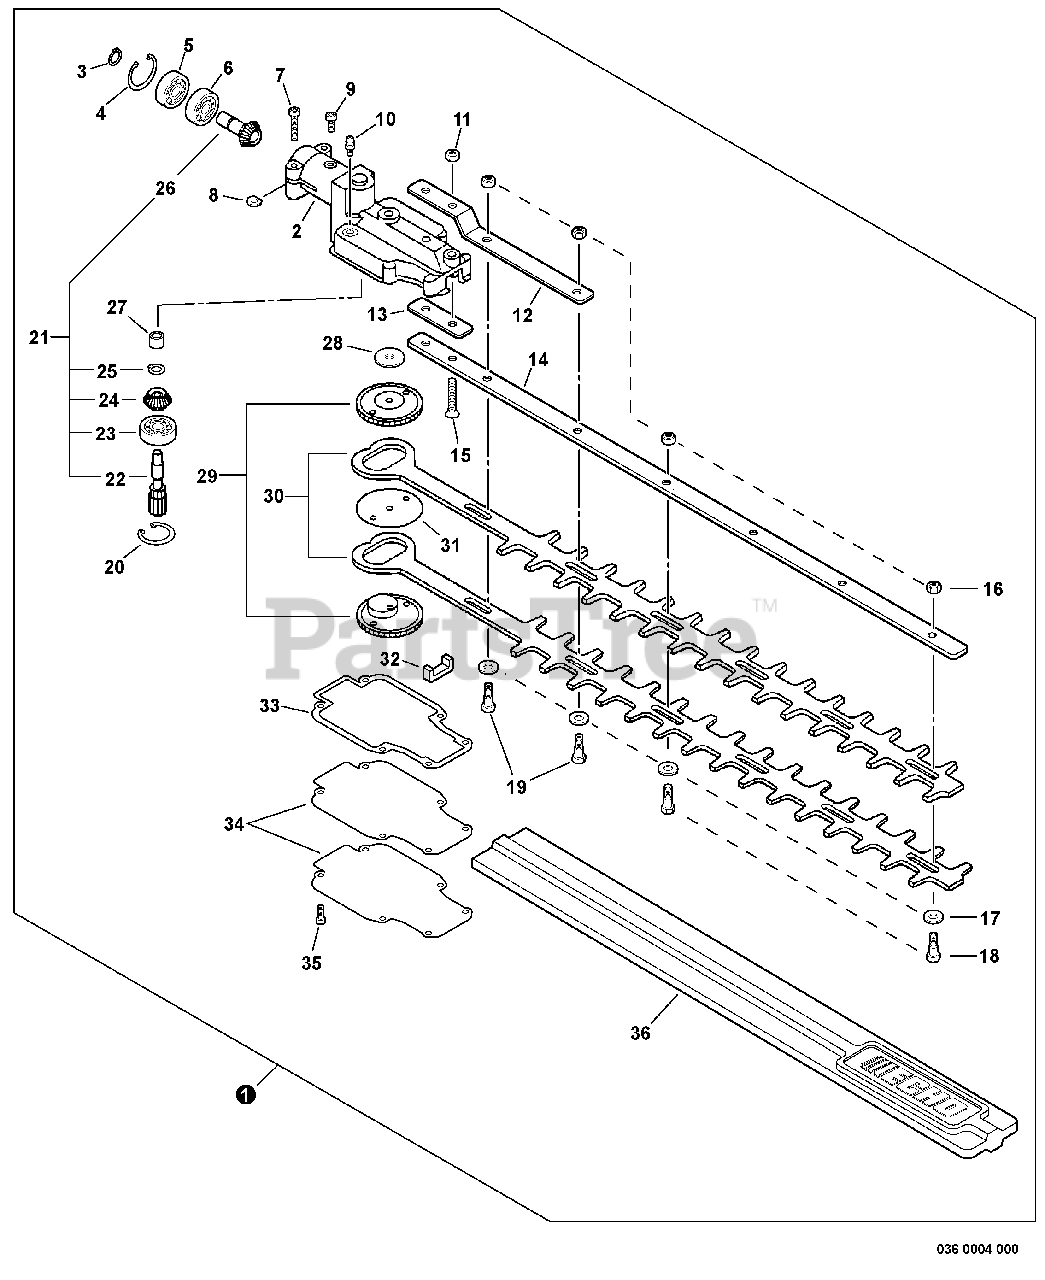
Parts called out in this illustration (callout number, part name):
1	GEAR CASE ASSY
2	CASE, GEAR - UPPER
3	RING, RETAINING - 12
4	RING, RETAINING - 24
5	BEARING, BALL - 6901Z
6	BEARING, BALL - 6901
7	SCREW - 5X28
9	SCREW - 5X12
10	FITTING, GREASE
11	LOCKNUT - 6
12	BRACKET, BLADE
13	PLATE
14	SUPPORT, BLADE
15	SCREW - 6X35
16	LOCKNUT - 6
17	WASHER - 6
18	BOLT - 6
20	RING, RETAINING - 24
21	SPUR GEAR SET
22	GEAR - SHAFT
23	BEARING, BALL - 6901
24	GEAR - BEVEL
25	RING, RETAINING
26	GEAR - BEVEL
27	BEARING, NEEDLE
29	GEAR - SPUR
30	BLADE, TRIMMER
32	SEAL, FELT
33	GASKET, GEAR CASE
34	LID, GEAR CASE
35	SCREW - 4X12
36	COVER, BLADE
